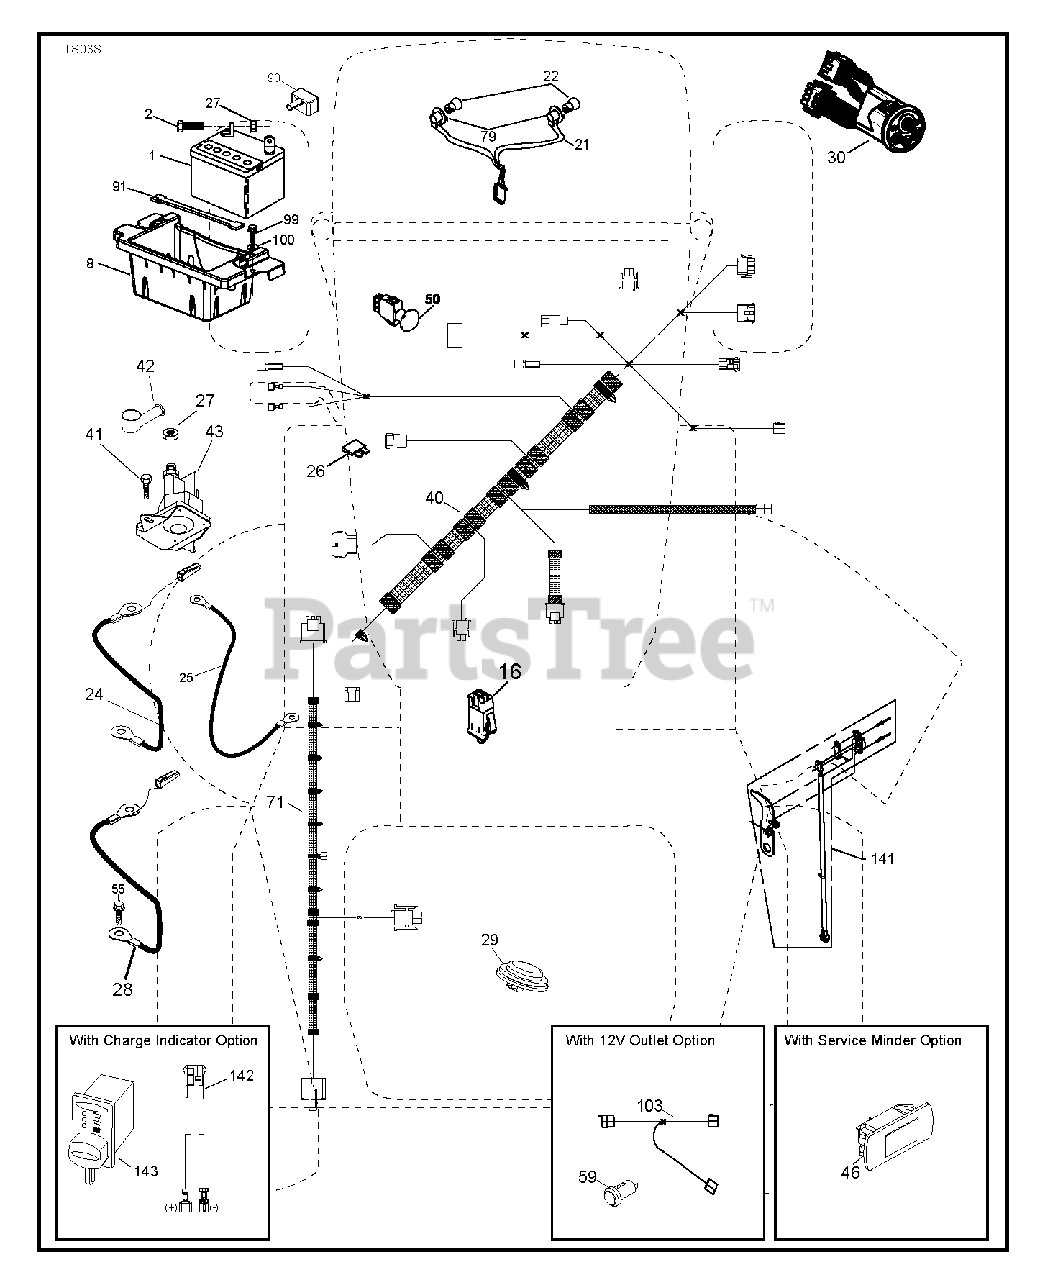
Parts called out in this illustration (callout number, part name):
1	REPL BY 532 12 38-99
8	BOX.BATTERY.MOUNT.FRONT.LT
16	SWITCH INTERLOOK PUSH-IN
21	HARNESS.W/LIGHT SOCKET
22	LIGHTBULB
25	CABLE.STARTER.6G.BL/RED.17.5
26	FUSE 20AMP
27	NUT
28	CABLE GROUND, BATT TO HARN
29	OPC Seat Switch, Grey Button/Cap
30	Smart Switch Kit, My14 Tractor
40	HARNESS.DASH.EL.SIS.RECT.FBAT
41	SCREW
42	TERMINAL COVER
43	SOLENOID.W/BRASS.PLUNG
46	GUAGE.SRVCMNDR.HRMTR.
50	PTO SWITCH
55	SCREW 5/16"
71	HARNESS.CHAS.TEX.SIS.FBAT.TWIN
79	BULB HOLDER ASM.
90	COVER.TERMINAL.BATTERY
91	STRAP, BATTERY MOUNT
99	SCREW HEXWSHR 1/4-20X3/4
141	KIT.G700/G730.ROS.SERV(71750)
